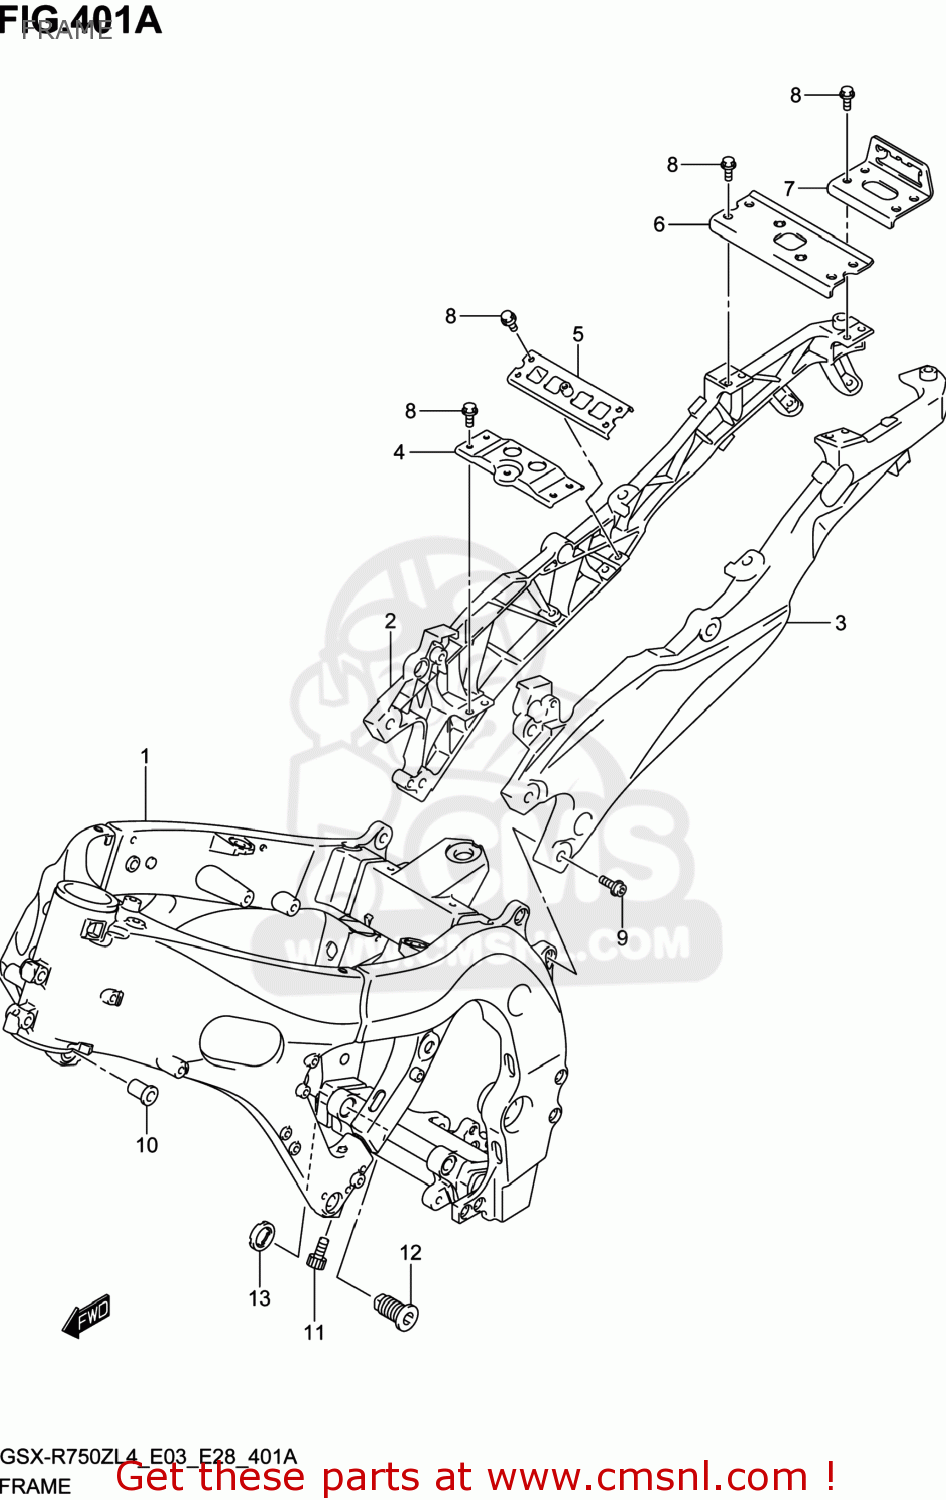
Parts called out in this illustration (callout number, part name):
1	FRAME(BLACK)
2	RAIL,SEAT,R(BLACK)
3	RAIL,SEAT,L(BLACK)
4	BRIDGE,SEAT RAIL FR
5	BRIDGE,SEAT RAIL LWR
6	BRIDGE,SEAT RAIL UPR
7	BRIDGE,SEAT RAIL RR
8	BOLT(6X12)
9	BOLT,SEAT RAIL
10	SPACER,ENGINE MOUNTING
11	BOLT(8X32)
12	BOLT,CRANK CASE ADJUST
13	NUT,ADJUST BOLT
